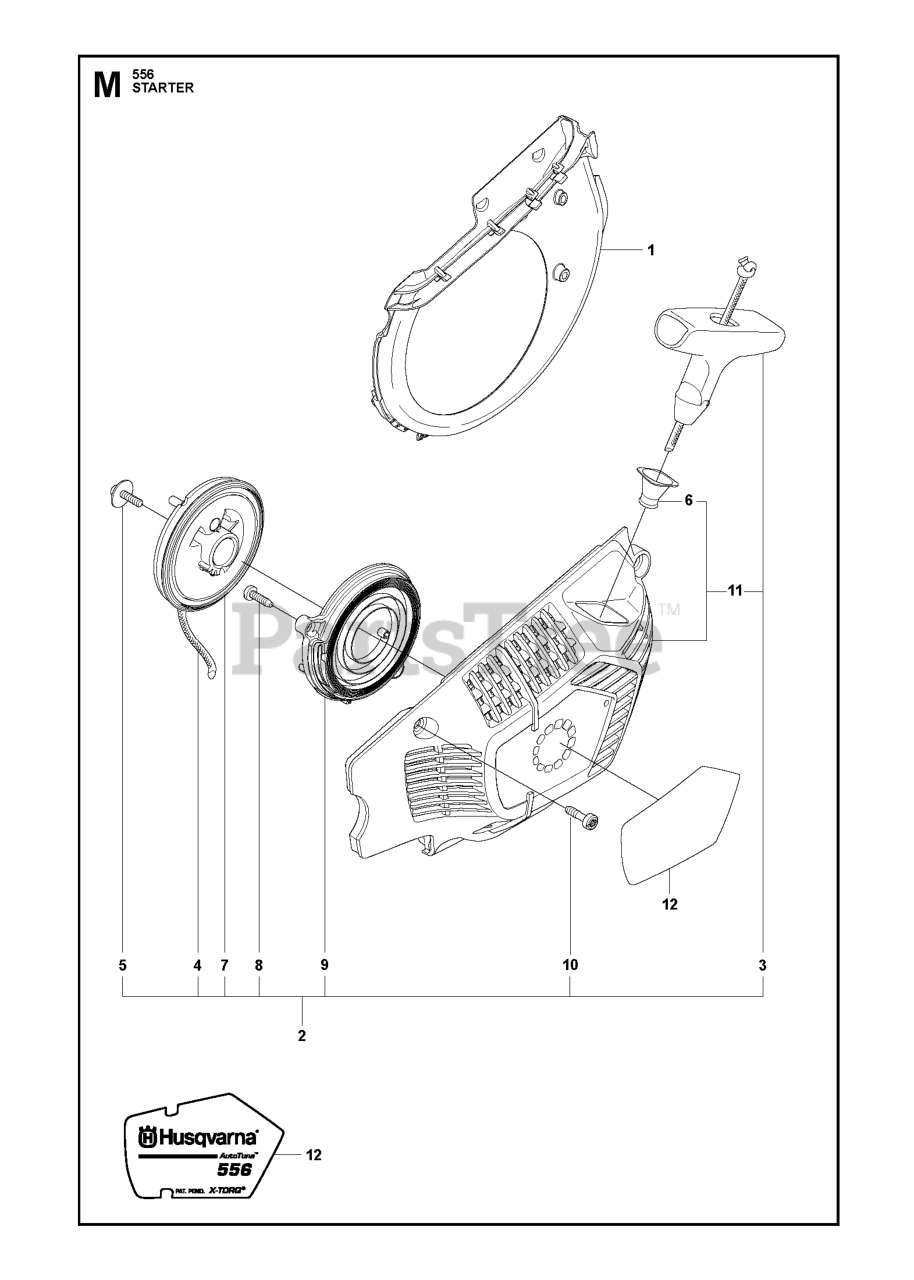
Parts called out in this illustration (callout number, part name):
1	SEAT.TH150.MS498.GRY.HUSQ.TEX
2	BRKT.PIVOT.FENDER
3	STRAP
6	NUT
7	SPRING COMPRESSION
8	BOLT.5/16-18UNCX3/4 W/SEMS.BLK
10	PAN.ASM.SEAT.3PT
21	BOLT.SHOULDER.5/16-18
37	NUT.71038.31-18.HEX.NYLOCK
40	HANDLE.SLIDE.SEAT.TEX.BLACK
41	SPRING.LATCH.SEAT.TEX
44	WASHER 13/32 X 2-3/8 X 12GA
